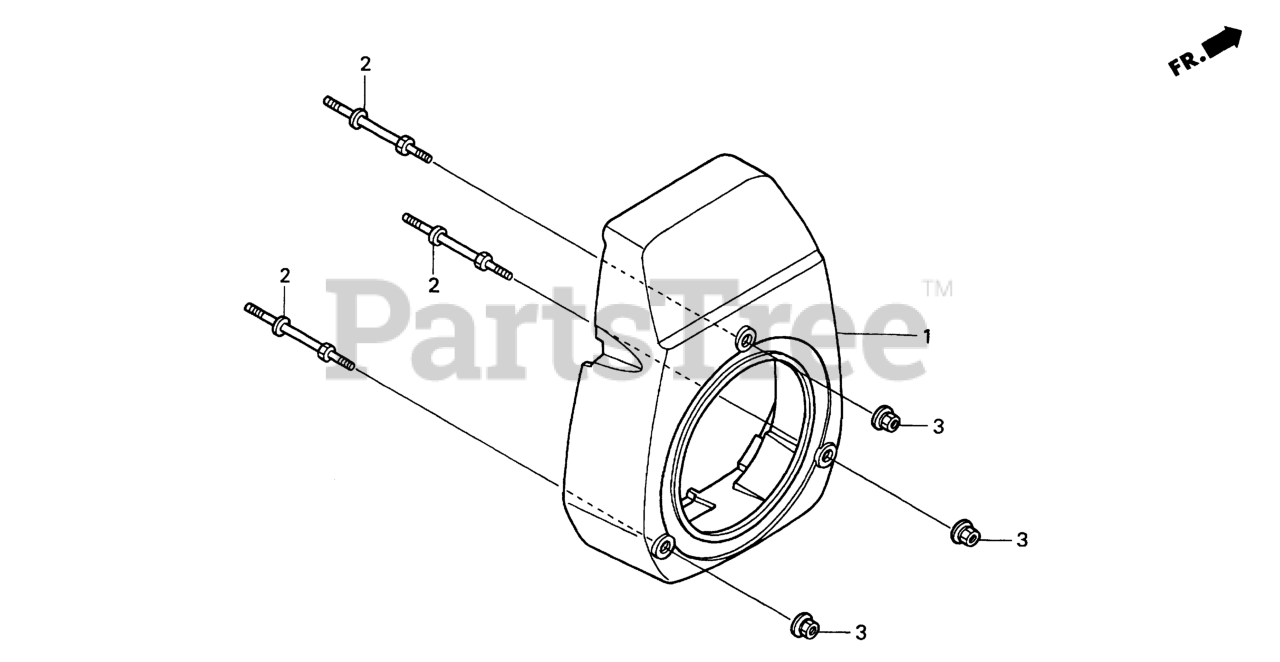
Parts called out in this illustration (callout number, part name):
1	COVER, FAN *R8* (BRIGHT RED)
1	COVER, FAN *R280* (POWER RED)
2	BOLT, STUD
3	NUT, FLANGE (6MM)
